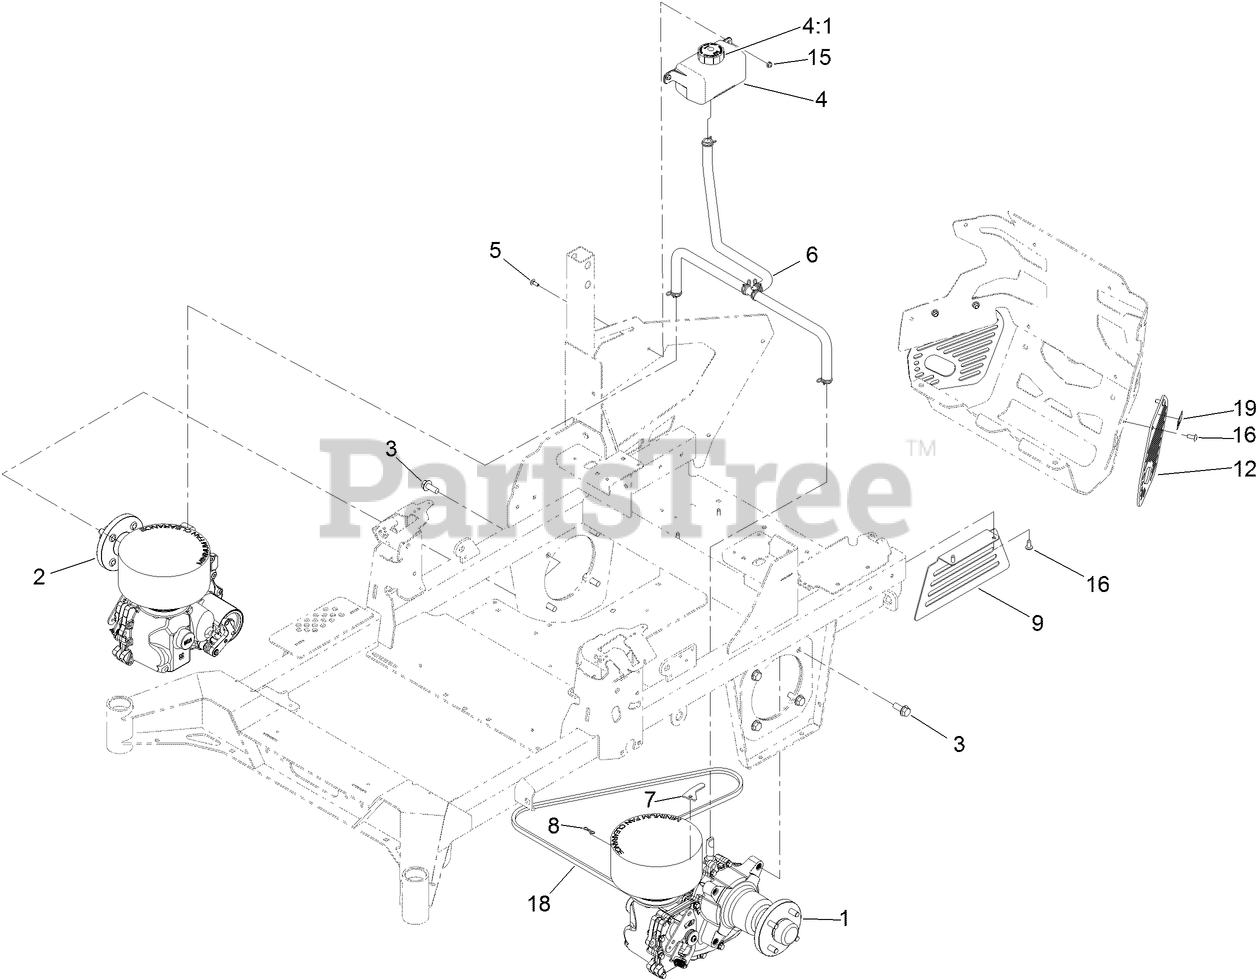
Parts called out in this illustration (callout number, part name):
1	LH TRANSAXLE ASM
2	RH TRANSAXLE ASM
3	SCREW-HHF
4	HYDRAULIC RESERVOIR ASM
4:1	CAP-RESERVOIR, HYD
5	SCREW-CARR
6	ASM-HOSE, HYDRAULIC
7	PLATE-LEVER, BYPASS
8	PIN-COTTER, LOCKING
9	GUARD-CLUTCH
12	GUARD-MUFFLER, TE
15	NUT-HF
18	BELT-V
19	DECAL-WARNING
